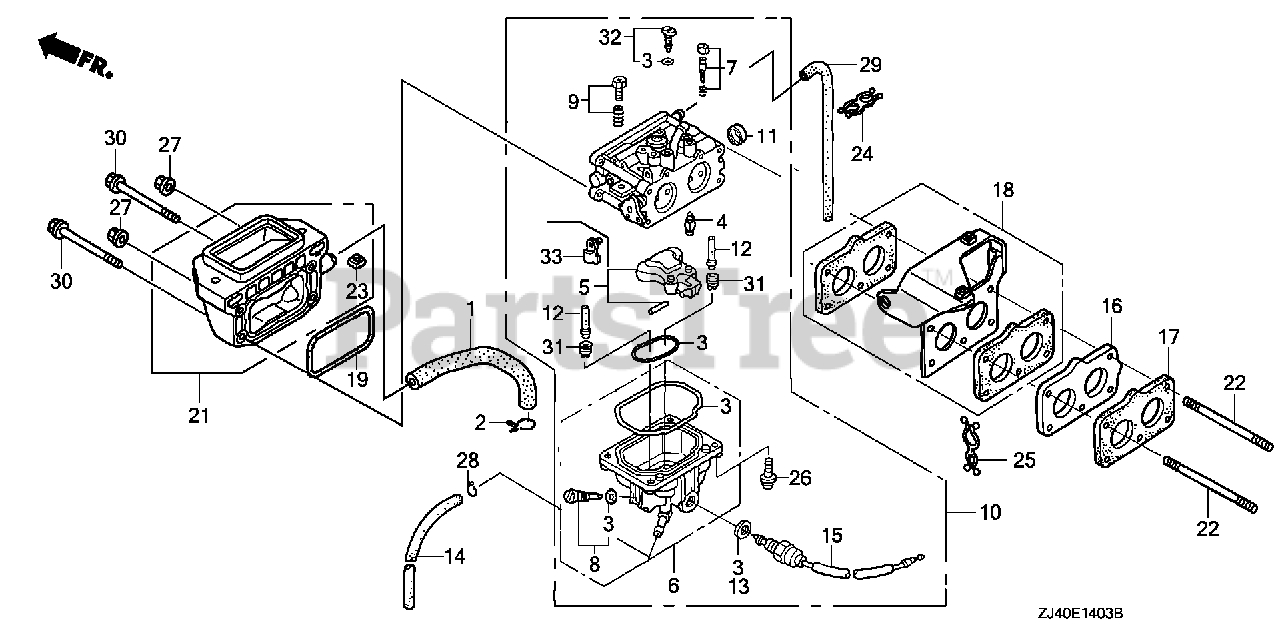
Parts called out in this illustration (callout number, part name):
1	TUBE, BREATHER
2	CLIP, BREATHER TUBE
3	GASKET SET
4	VALVE SET, FLOAT
6	CHAMBER SET, FLOAT
7	SCREW SET, PILOT
8	SCREW SET, DRAIN
9	SCREW SET, THROTTLE
10	CARBURETOR ASSY. (BK04A A)
11	CAP, CHOKE DUST
12	NOZZLE, MAIN
13	WASHER, PLAIN
14	TUBE, DRAIN
15	VALVE ASSY., SOLENOID (KEIHIN)
16	INSULATOR, CARBURETOR
17	GASKET, CARBURETOR
18	STAY, FUEL PUMP
19	GASKET, AIR CLEANER
21	ELBOW, AIR CLEANER
22	BOLT, STUD (6X113)
23	NUT, INSERT (6MM)
24	CLIP, WIRE HARNESS
25	CLIP, PURSE LOCK
26	SCREW, PAN (4X12)
27	NUT, FLANGE (6MM)
28	CLIP, TUBE (B8)
29	BULK HOSE, VACUUM (4.5X1000) (4.5X540)
30	BOLT, FLANGE (6X115)
31	JET, MAIN (#82)
31	JET, MAIN (#85)
31	JET, MAIN (#88)
32	JET SET, PILOT (#40)
33	ARM, THROTTLE LINKAGE
